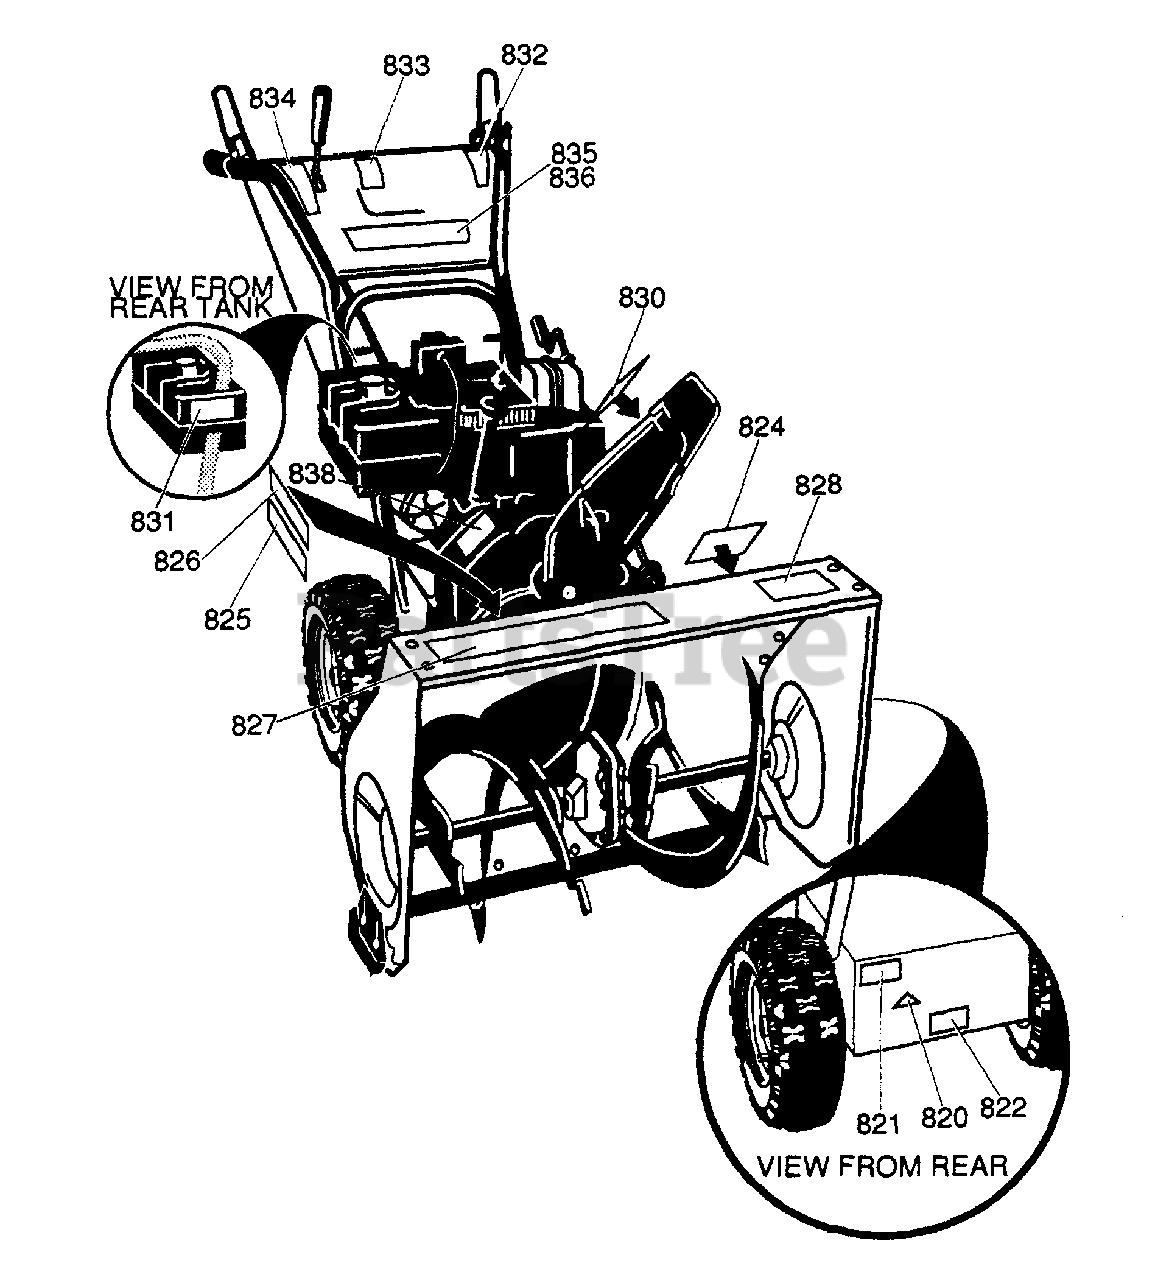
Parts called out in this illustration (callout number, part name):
820	REFERENCE ONLY
821	REFERENCE ONLY
822	DECAL, OVER ADJ OF DISC
824	DECAL, DANGER FOOT SYM
825	DECAL, DUAL STAGE
827	DECAL, HUSQVARNA 8/26 AUG END
828	DECAL, HUSQVARNA 8/26 AUG END
830	DECAL, DANGER FINGER
831	DECAL, IMPORTANT FREE IMPEL
832	DECAL, TRACTION DRIVE #6099
833	DECAL, SNOW CONDITIONS
834	DECAL, GEAR SELECTOR/AUGER
835	DECAL, HUSQVARNA 8/26 PANEL
838	DECAL, BELT ADJ
